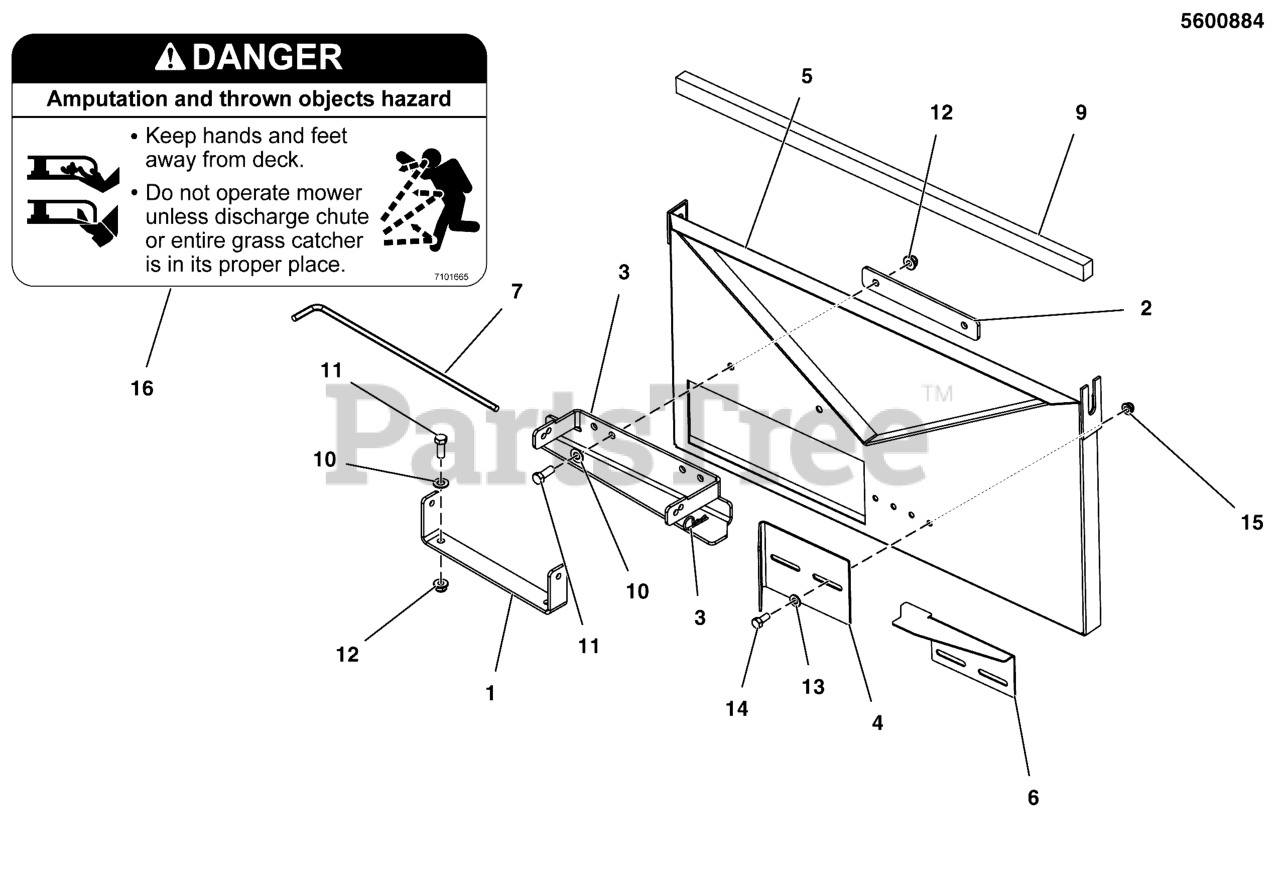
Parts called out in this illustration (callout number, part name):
1	PLATE, BAGGER MNT BRKT, DECK, 36"-BLK
2	PLATE,BAGGER MNT BRACKET,SUPRT,32/36-BLK
3	PLATE, BAGGER MOUNT BRACKET, 32/36"-BLK
4	PLATE, BLOCK OFF PLATE, 32/36"-BLK
5	WELD, BAGGER MOUNT, 32/36" - BLK
6	PLATE, 32/36 BAGGER, BLOCK-OFF - BLK
7	ROD, QUICK CONNECT
8	PIN, HAIR, .0915 X 1-7/8
9	FOAM, 3/4 X 1 X 28.25
10	WASHER, 3/8 SAE
11	BOLT, 3/8-16 X 1" GD5 CZ
12	NUT, 3/8-16 HEX NYLOCK FLANGE
13	WASHER, 5/16" SAE
14	BOLT, 5/16-18 X 3/4 GD5
15	NUT, 5/16-18 HEX NYLOCK FLANGE
16	DECAL, DANGER DO NOT OPERATE W/O DEFLECT
